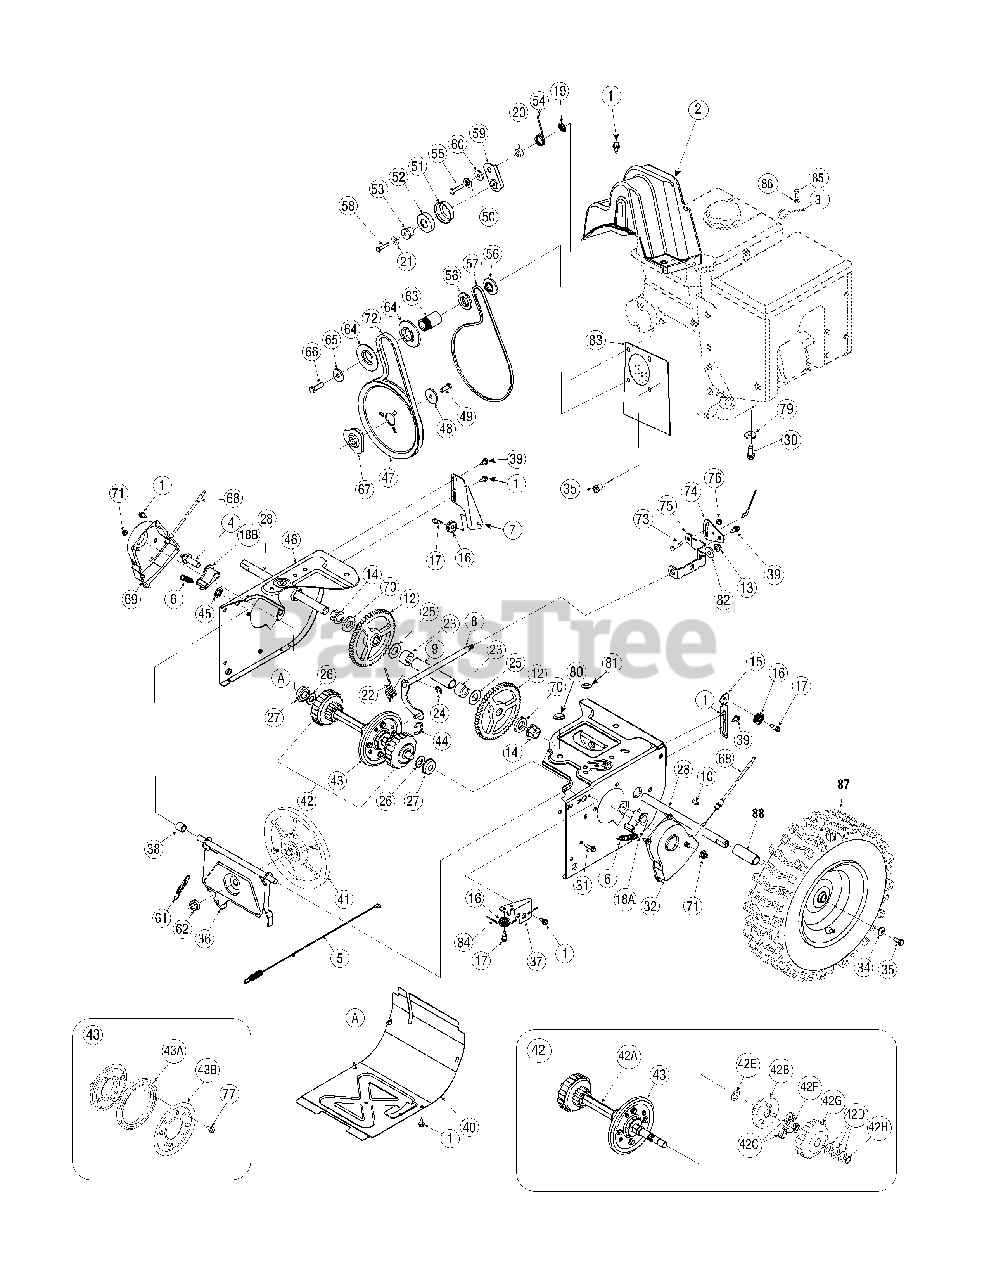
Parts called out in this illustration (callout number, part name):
1	Hex Wash Hd TT Scr. 1/4-20 x .625
2	Belt Cover (w/277 cc - 357 cc engines)
2	Belt Cover (w/208 cc engines)
3	Cable Control Wire
4	Drive Shaft Actuator
5	Drive Clutch Cable 44.83" Lg.
6	Extension Spring .5 OD x 1.71 Lg.
7	Guide Bracket - Drive Cable
8	Shift Rod Ass’y
9	Axle Support Tube
10	#9 HI-Pro Key 3/16 x 3/4 Dia HT
13	Flange Lock-Nut 5/16-18 Gr. F Nylon
14	Hex. Flange Bearing.751" ID
15	Guide Bracket - Auger Cable
16	Cable Guide Roller
17	Hex Shld.Scr.1/4-28 x .375
18A	Dogg Assembly - LH
18B	Dogg Assembly - RH
19	Push Nut
20	Spacer .340 x .750 x .360" Lg.
21	L-Wash 1/4 ID
22	Torsion Spring .750 ID x .968" Lg.
24	Retaining Ring
25	Flat Washer .760 ID x 1.49 OD
26	Flat Washer .580 x 1.125 x .080
30	Hex Wash HD Tap Scr 3/8-16 x .88
31	Hex Bolt 1/4-20 x 1.00
34	Cupped Washer .345 ID x .88 OD x .060
35	Shoulder Screw .50 x .145: 5/16-24
37	Auger Cable Guide Bracket
38	Spacer .513 ID x 1.0
39	Shoulder Screw .373 x .105:TT 1/4-20
41	Friction Wheel Disc Assembly
42	Drive Shaft Assembly (w/o Friction Wheel Ass'y)
42A	Hex Drive Shaft (500)
42B	Planetary Carrier Ass'y
42D	Flat Washer .58 x 1.12 x .02
42E	Flat Washer 5/8 ID x 1.0 OD
42G	Ring Planetary Gear Ass'y (500)
42H	Retaining Ring 1.56 diam.
43	Friction Wheel Assembly
43A	Friction Wheel Rubber
43B	Friction Plate
44	Retainer Ring
45	Cap Speed Nut 1/4 Rod
46	Wheel Drive Frame
48	Flat Washer .34 x 1.50 x .150
49	Hex Bolt 5/16-24 x 0.875
50	L-Wash 5/16 ID
51	Bearing Sleeve
52	Ball Bearing 20 x 47 x 14:6204:DS
54	Torsion Spring .850 ID x .354" Lg.
55	Hex HD. Cap Scr. 5/16-24 x 1.25 Lg.
57	Belt 3/8 x 34.13" Lg.(w/208 cc engines)
57	Belt 3/8 x 35.68" Lg.(w/277cc - 357cc engines)
58	Hex Bolt 1/4-20 x 1.25
59	Wheel Drive Idler Bracket
60	Shoulder Spacer
61	Extension Spring 3/8 OD x 2.50
62	Jam L-Nut 5/8-18 Gr. 5 Nylon
63	Spacer .875 ID x 1.185 OD
64	Pulley Half
65	Flat Washer .40 ID x 1.25 OD x .160
66	Hex Screw 3/8-24 x 1.25
67	Pulley Adapter
68	Steering Cable
71	Flange Lock-Nut 3/8-16 Gr. F Nylon
72	Belt .5 x 35.0" Lg. (w/208 cc engines)
72	Belt .5 x 37.0" (w/277cc - 357cc engines)
73	Hex Bolt 1/4-20 x .62 Gr. 5
74	Pivot Bracket
75	Shift Bracket
76	Flange Lock-Nut 1/4-20 Gr. F Nylon
77	Hex Wash. Hd. TT Scr. 1/4-14 x .625
79	Flat Washer .38 x 1.38 x .125 (Rear left hole)
82	Flat Washer .469 x .875 x .105
83	Cover Plate (optional)
84	Auger Clutch Cable 47.23" Lg.
85	Hex. Hd. Cap Scr. M8-1.25:20 Gr. 8
86	Flat Washer .330 ID x .630 OD x .0635
87	X-Trac LH 16 x 4.8 x 8
87	X-Trac RH 16 x 4.8 x 8
87	X-Trac LH 16 x 6.5 x 8
87	X-Trac RH 16 x 6.5 x 8
87	X-Trac LH 15 x 5 x 6
87	X-Trac RH 15 x 5 x 6
88	Spacer
